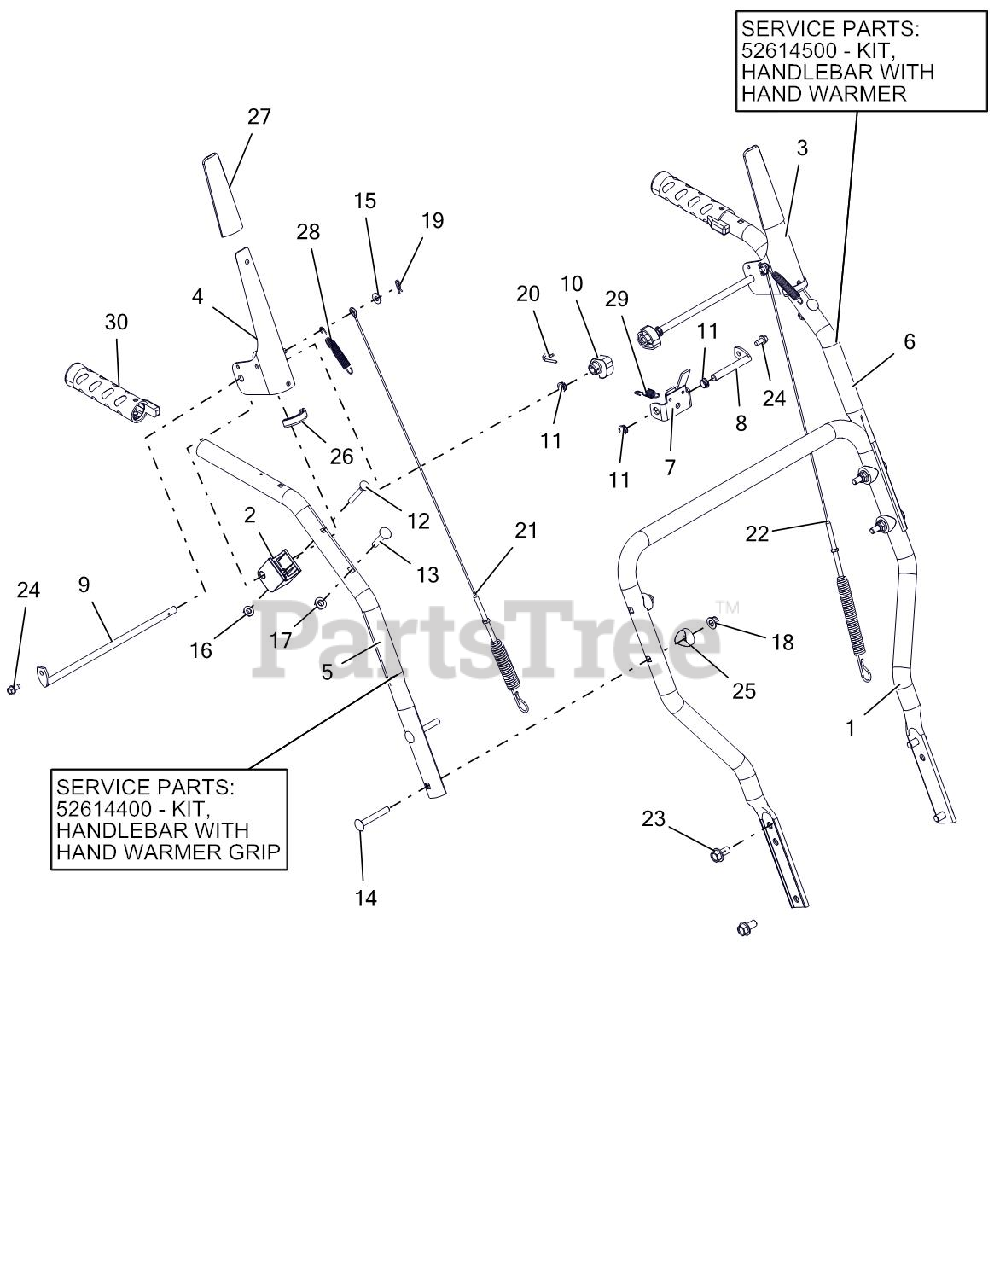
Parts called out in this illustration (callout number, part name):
1	HANDLEBAR, LOWER
2	BLOCK, CLUTCH PADDLE
3	LEVER, CLUTCH-LH
4	LEVER, CLUTCH-RH
5	HANDLEBAR, UPPER - RH
5	KIT, HANDLEBAR HW RH
6	HANDLEBAR, UPPER - LH
6	KIT, HANDLEBAR HW LH
7	BRACKET, INTERLOCK ARM
8	ROD, PIVOT - INTERLOCK
9	ROD, PADDLE MOUNT - PRO
10	CAM, INTERLOCK
11	BUSHING, POLYLINER-.38 SNAPIN
12	BLT-RDHDXLSQNK .25-20X2.0 G5YZ
13	@BLT-RDHDSQNK .31-18X1.50 G5YZ
14	@BLT-RDHDSQNK .31-18X2.25 G5YZ
15	@WSHR-FL-STL.281X.62X.065 YWZC
16	@NUT-LK-CTR-FLG .25-20 YWZC
17	@NUT-LK-TOP-FLG .31-18 YWZC
18	@NUT-LK-NYL-FLG .31-18 YWZC
19	PIN-HAIR INT .06X.18X.77
20	PIN, SPRING CLIP
21	CABLE, AUGER (DELUXE & PRO)
22	CABLE, UPPER TRACTION
23	BLT-SERHFWH .38-16X.75 YWZC
24	SCR-TAP .25-20X.50 HWH TR YWZ
25	SPACER, HANDLEBAR
26	EDGING, CLUTCH PADDLE - 2.00"
27	SLEEVE, CLUTCH PADDLE-GRAY
28	SPRING, EXTENSION
29	SPRING-EXT .047X.438X1.45
30	KIT, HANDWARMER - W/GLUE
